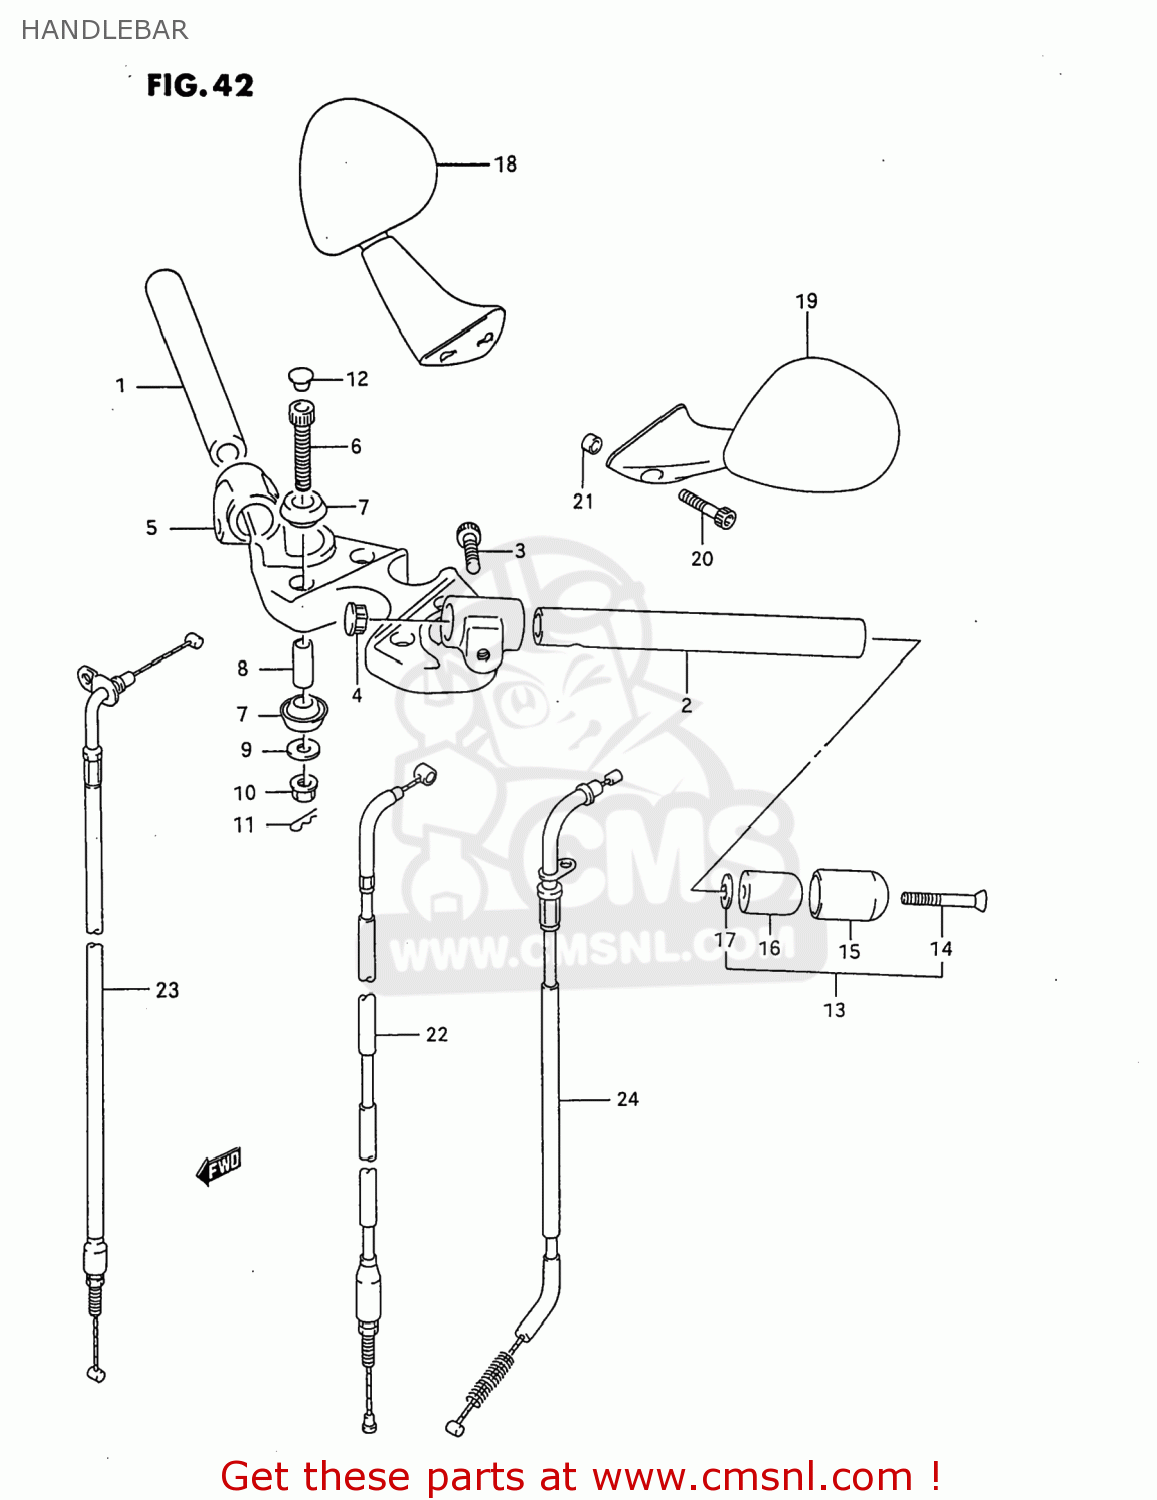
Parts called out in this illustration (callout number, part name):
1	HANDLEBAR,R
2	HANDLEBAR,L
3	BOLT
4	CAP,HANDLEBAR
5	HOLDER,HANDLEBAR
6	BOLT(10X77)
7	RUBBER,HANDLE HOLDER
8	SPACER,HANDLEBAR BRACKET
9	WASHER(10.5X30X3.2)
10	NUT 10MM
11	CLIP
12	CAP(OD:10)
13	BALANCER SET,HANDLEBAR
14	SCREW
15	CAP,HANDLE BALANCER
16	BALANCER,HANDLEBAR
17	SPACER,BALANCER
18	MIRROR ASSEMBLY,REAR VIEW
19	MIRROR ASSEMBLY,REAR VIEW
20	BOLT
21	SPACER(6.5X9X3.8)
22	CABLE ASSY,CLUTCH
23	CABLE ASSY,THROTTLE
24	CABLE,STARTER
